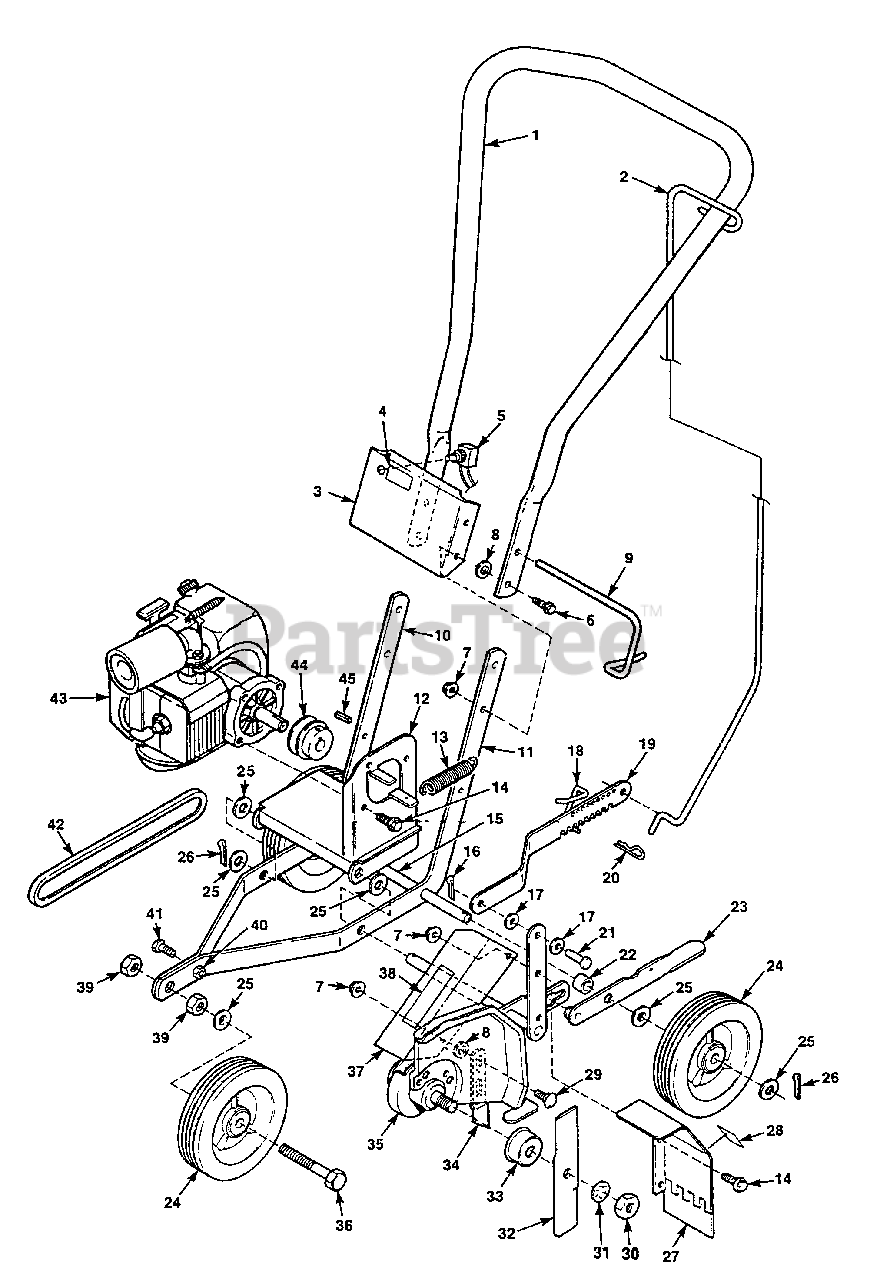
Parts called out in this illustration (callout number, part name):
1	HANDLE- Edger
2	CONTROL- Depth
3	COVER- Handle
4	DECAL- Stop
5	SWITCH- Off
6	BOLT- (1/4-20 x 1")
7	NUT- Flange (1/4-20)
8	WASHER- Flat (1/4")
9	HANDLE- Quick Release
10	FRAME- R.H. Side
11	FRAME- L.H. Side
12	BRACKET- Engine mounting
13	SPRING- Belt
14	BOLT- Sems hd. (1/4-20 x 5/8")
15	AXLE- Rear
16	PIN- Cotter
17	WASHER- Flat (5/16")
18	RETAINER- Ratchet
19	CONTROL- Ratchet Depth
20	PIN- Hair
21	PIN- Clevis
22	SPACER- Axle
23	PEDAL- Depth Control
26	PIN- Cotter
27	FLAP- Debris
28	DECAL- Safety
29	BOLT- Corr. (1/4-20 x 5/8")
30	NUT- Jam (5/8-18)
31	WASHER- Int. tooth (5/8")
32	BLADE- Edger
33	WASHER- Dust Shield
34	FINGER- Guide
35	HEAD- Cutter
36	BOLT- (1/2-13 x 3")
37	GUARD- Pulley
38	DECAL- Warning
39	NUT- Lock (1/2-13)
40	NUT- Lock (5/16-18)
41	BOLT- (5/16-18 x 3/4")
42	BELT- Drive
43	ENGINE
44	PULLEY- Engine
45	KEY- Square
